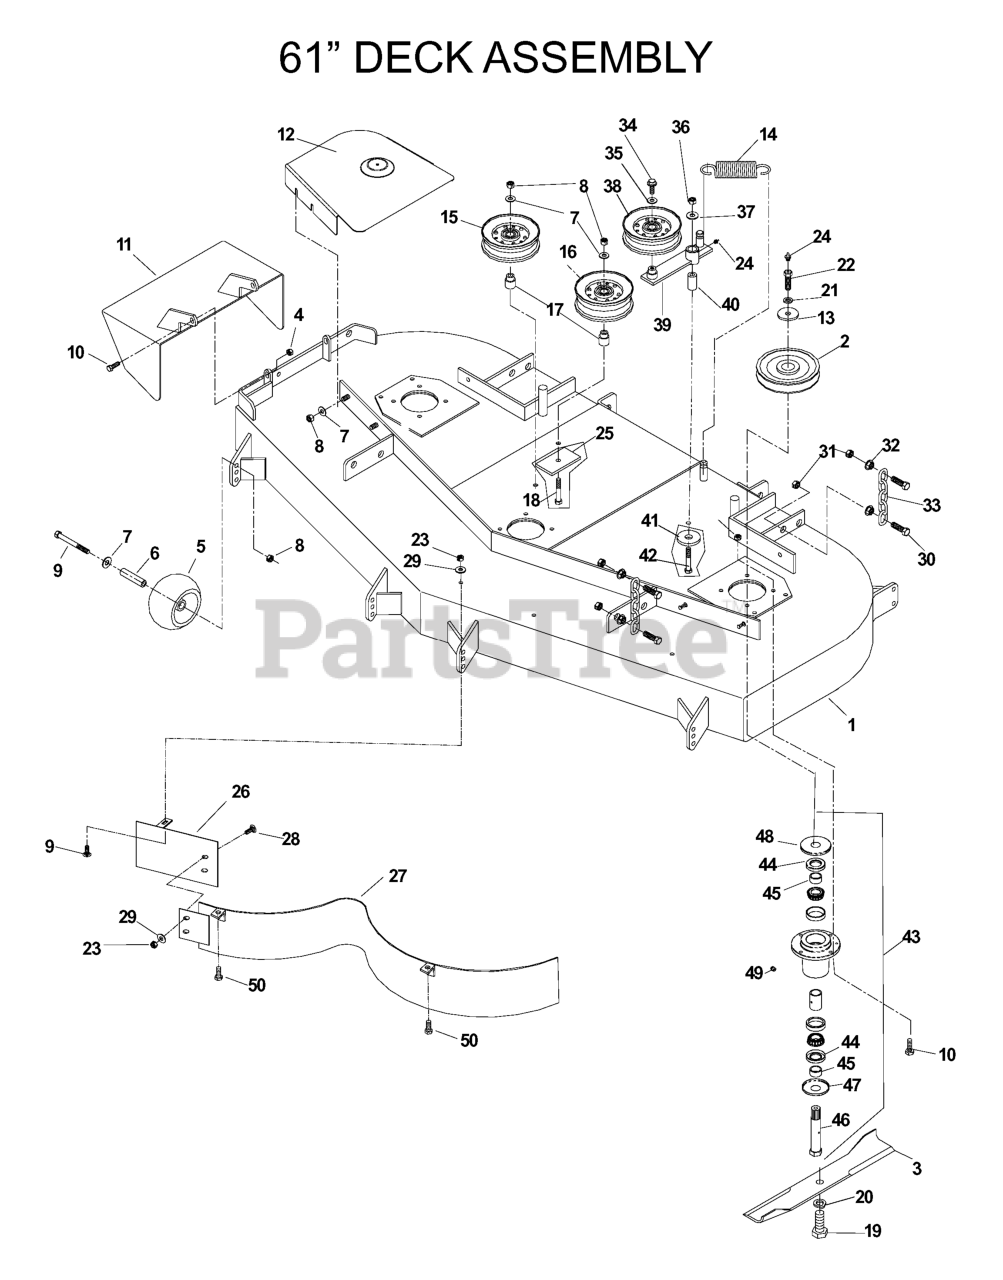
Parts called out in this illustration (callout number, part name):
2	SEALING RING
3	BALL BEARING
6	INSERT, CARTER
7	BALL BEARING
8	SEALING RING
9	CRANKCASE CPL
